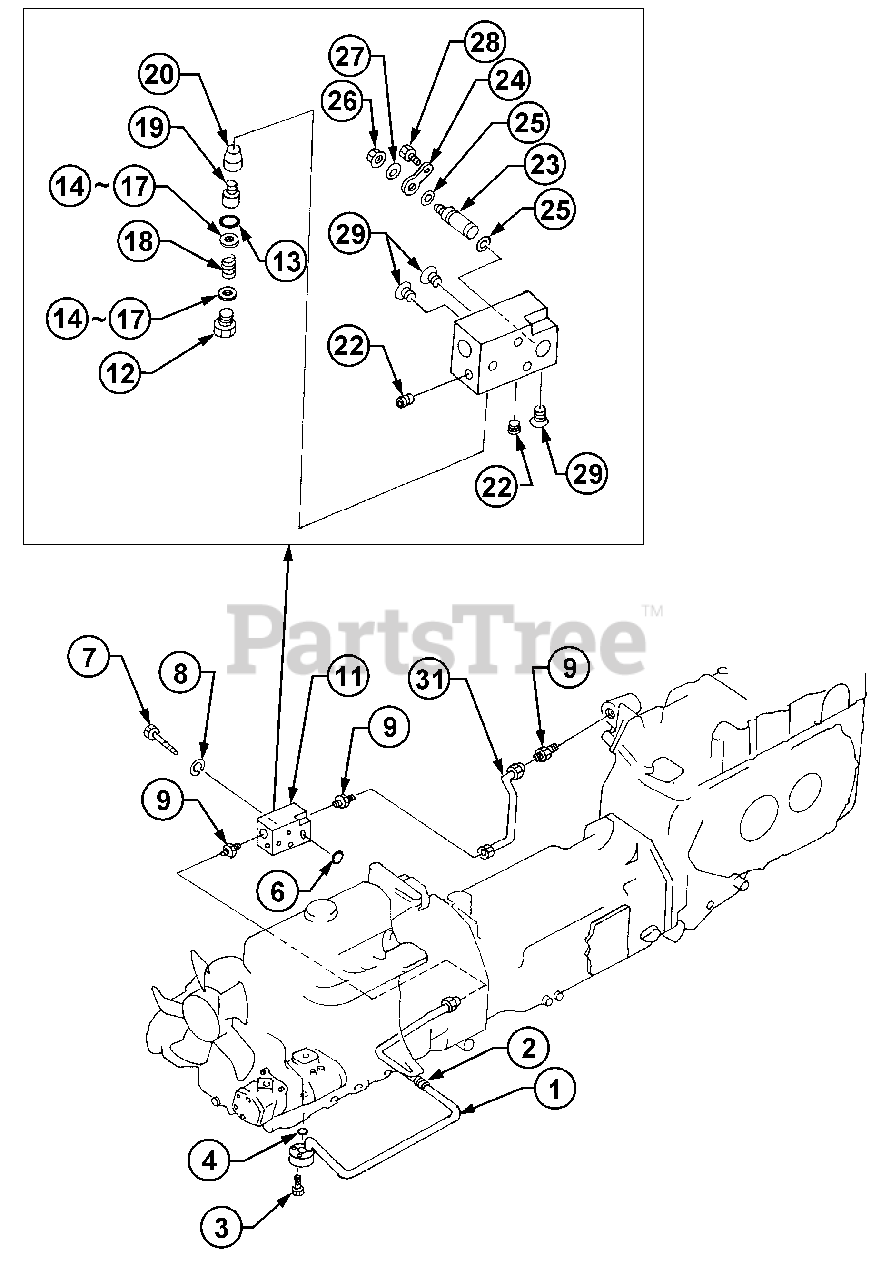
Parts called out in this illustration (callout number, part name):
1	Pipe D Assy
11	Block
28	Bolt, w/Washer
31	Pipe Delivery
